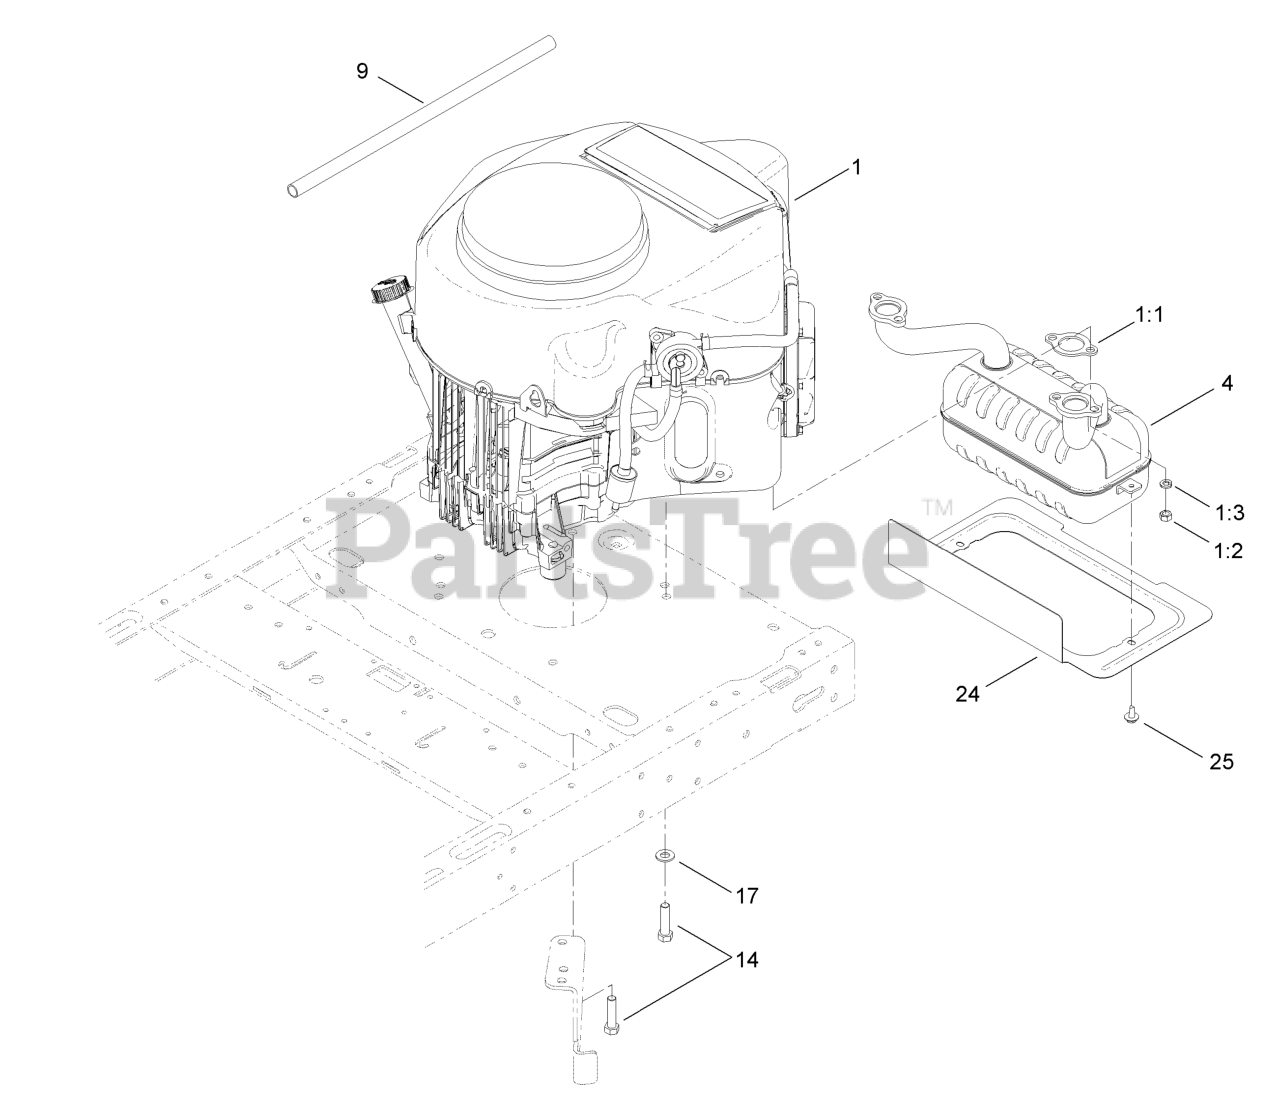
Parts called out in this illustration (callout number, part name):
1:1	GASKET-EXHAUST
1:3	WASHER-LOCK
4	MUFFLER-KAWASAKI
9	TUBE-DRAIN, OIL
14	BOLT-HH
17	WASHER-FLAT
24	SHIELD-HEAT
25	SCREW-HHFTF
